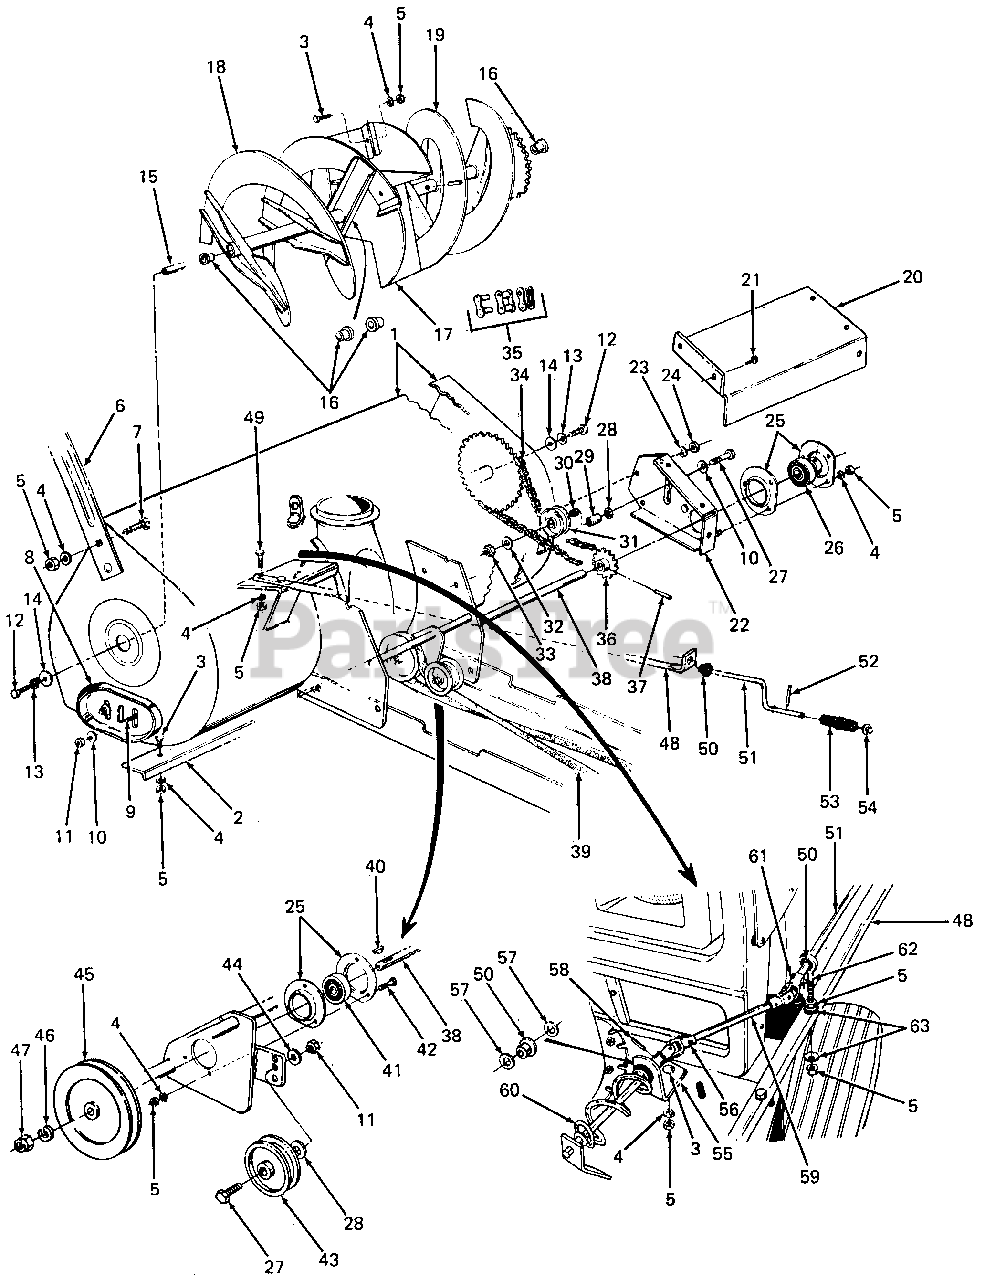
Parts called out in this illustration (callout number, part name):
1	Housing Assembly
4	Washer, Lock, 5/16
5	Nut, Hex, 5/16-18
7	Bolt, Carriage, 5/16-18 X .62 Lg
8	Shoe, Slide
9	Bolt, Carriage, 3/8-16 X .75 Lg
10	Washer, Bell, .380 X .88 X .06 Thk
11	Nut, Hex Jam, 3/8-16
12	Screw, Hex Cap, 1/2-13 X 1.25 Lg
13	Washer, Bell, .505 X 1.0 X .075 Thk
14	Washer, Flat, .531 X 1.25 X .100 Thk
15	Axle, Spiral
16	Bearing, Flange, .875 ID
24	Nut, Hex, 1/4-20
25	Flangette
26	Bearing, Self Aligning Ball
27	Screw, Hex Cap, 3/8-16 X 1.75 Lg
28	Washer, Flat, .406 X 1.25 X .157 Thk HDN
29	Bearing, Sleeve
30	Spacer, .377 X .50 X .830 Lg
31	Idler, Flat, 1.875 Dia
32	Washer, Flat, .385 X .87 X .06 Thk
33	Nut, Hex Center Lock, 3/8-16
34	Chain, #420 1/2" Pitch X 77 Links
35	Link, Master, #420 Chain
36	Sprocket - 14 Tooth
37	Pin, Spiral Spring, 5/16 Dia X 1.75 Lg
38	Shaft, Drive
39	V-Belt, 1/2 X 90.0 Lg
40	Key, #61 Hi-Pro, 3/16 X 5/8 Dia
41	Bearing, Ball, 3/4 ID
42	Screw, Hex Sems, 5/16-18 X .75 Lg
43	Pulley, Idler
44	Washer, Lock, 3/8
45	V-Pulley, 5/8-.75 ID X 6.00 OD
46	Washer, Lock, 3/4
47	Nut, Hex Jam, 3/4-10
50	Bushing
51	Crank, Chute, .374 X 34.5 Lg
52	Pin, Roll, 1/8 Dia X .63 Lg
53	Knob, Chute Crank
55	Bracket, Chute Crank
56	Block, Joint
57	Washer, Flat, .385 X .62 X .063 Thk
58	Pin, Spiral, 1/8 Dia X .812 Lg
59	Rod, Chute Crank Extension
60	Crank, Chute Worm
61	Pin, Cotter, 3/32 Dia X 1.0 Lg
62	Bolt, Eye, 5/16-18 X 3.0 Lg
63	Washer, Bell, .345 X .88 X .060 Thk
